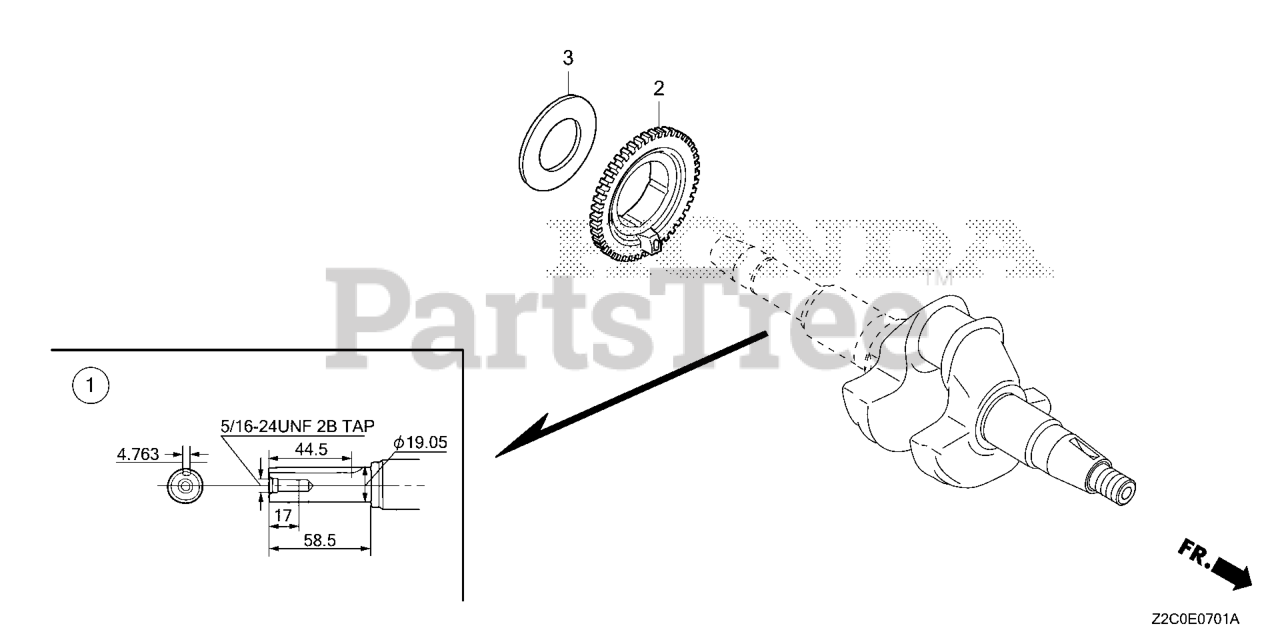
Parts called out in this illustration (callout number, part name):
1	CRANKSHAFT
2	PULLEY, TIMING BELT DRIVE
3	WASHER, THRUST
